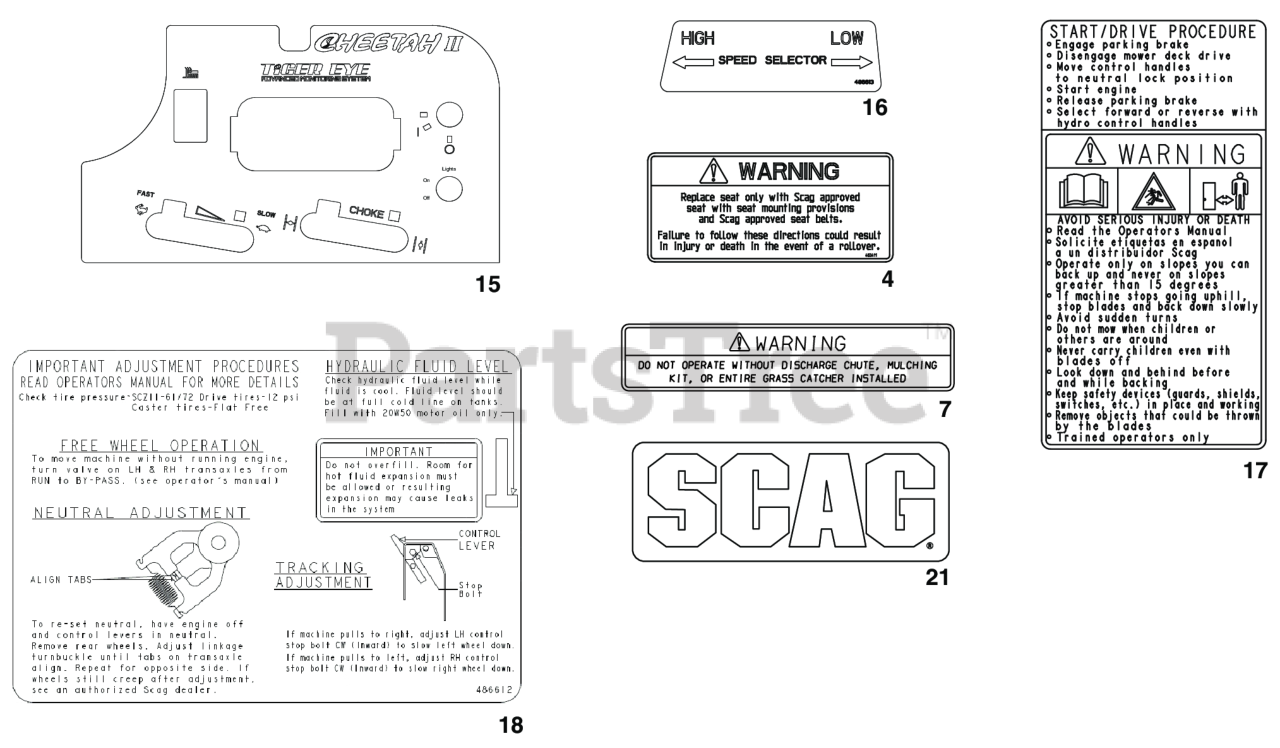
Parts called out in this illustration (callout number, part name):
4	Decal, Seat Replacement
7	Decal, Warning-Discharge
15	Decal, Instrument Panel - SCZII
15	Decal, Instrument Panel - SCZII - EFI
16	Decal, Speed Control
17	Decal, Start / Drive
18	Decal, Adjustments - SCZII
21	Decal, Scag - Fuel Tank
